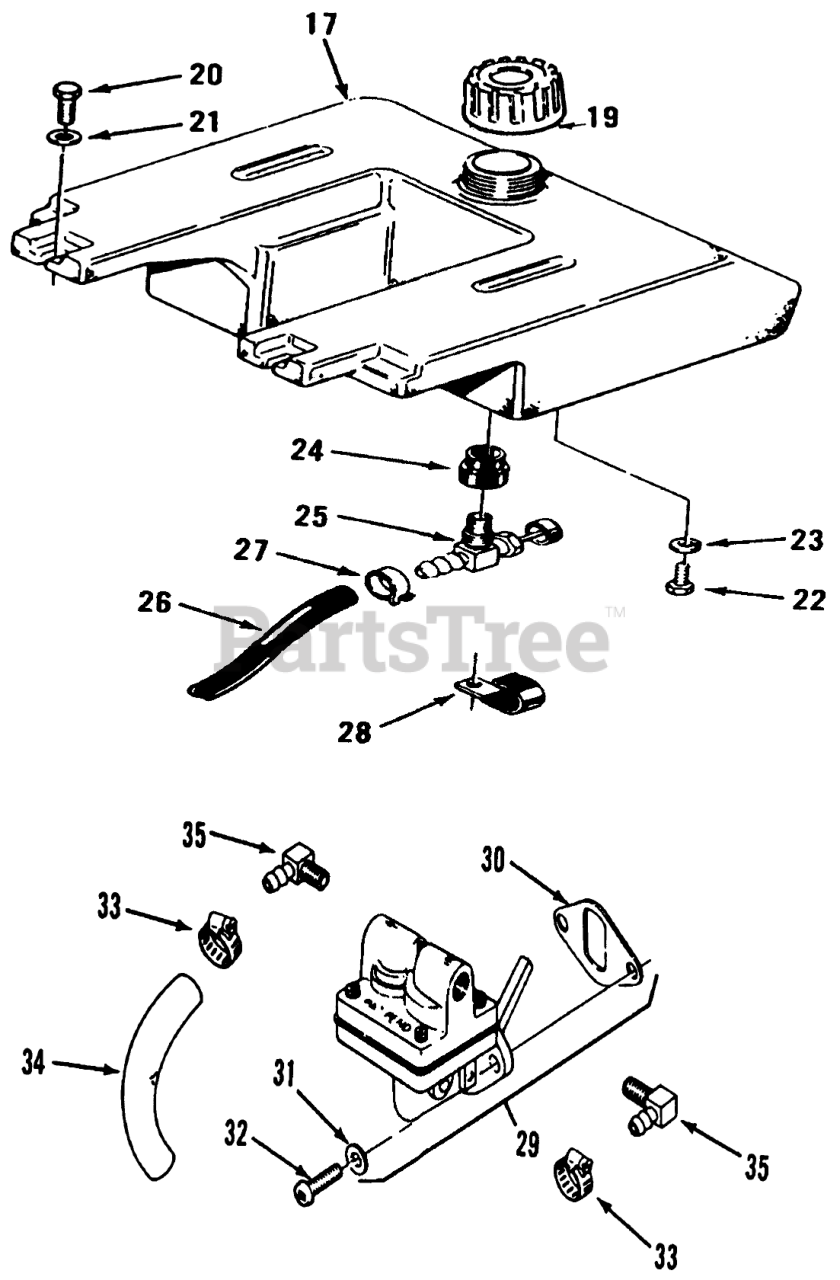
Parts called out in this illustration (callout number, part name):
17	TANK-FUEL
18	GAS CAP ASM
20	Bolt
21	Washer
22	Bolt
23	Lockwasher
24	BUSHING
25	VALVE-FUEL
26	Fuel Line 62
27	Clamp
28	Clamp
29	Fuel Pump Assy (Includes Items 30 & 31)
30	Gasket
31	Screw
32	Screw-Pozidrive
33	Clamp
34	Line-Fuel
35	Connector 90
